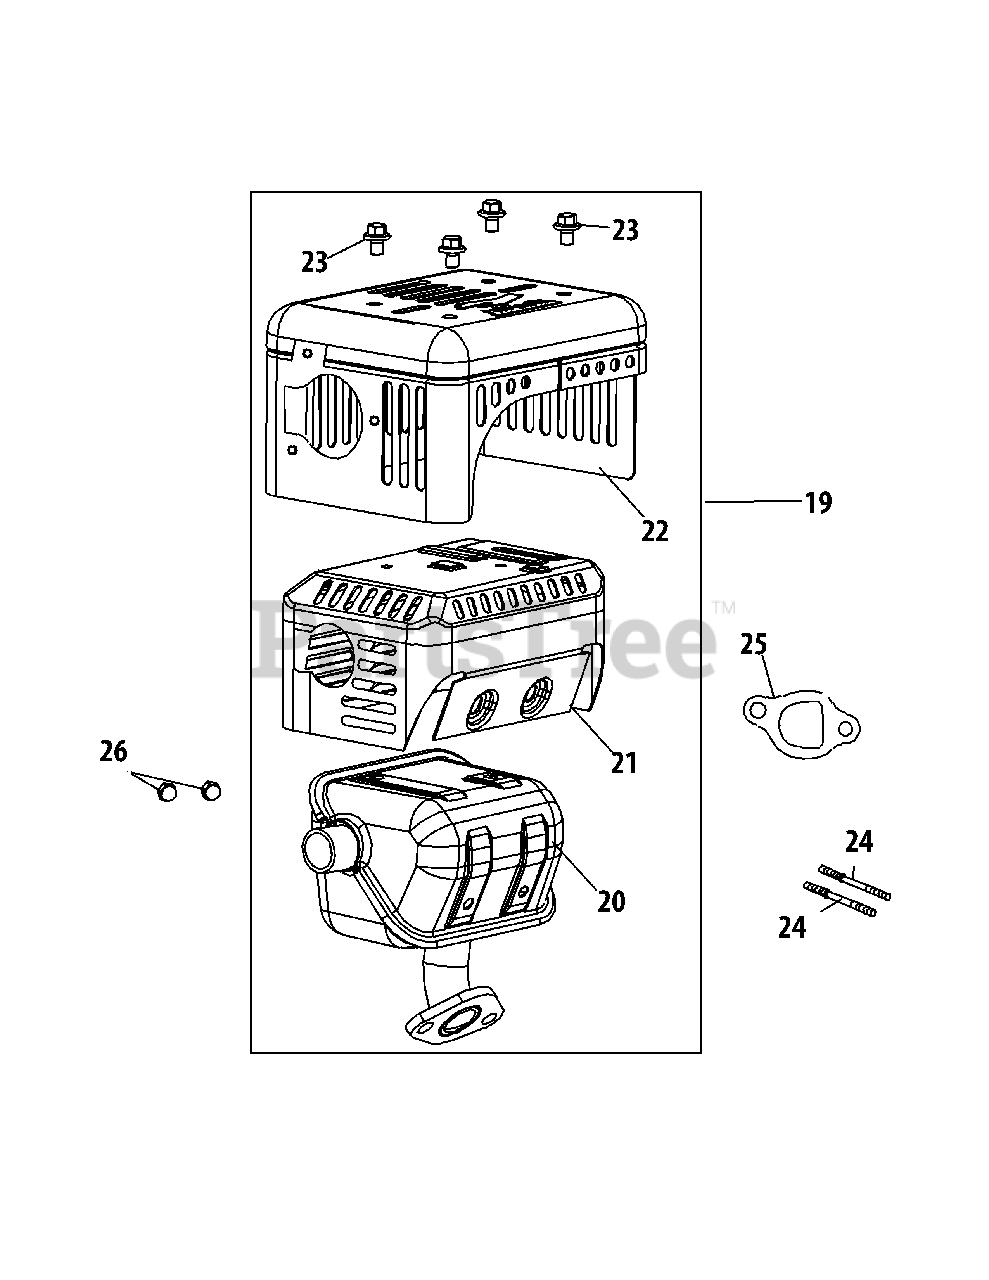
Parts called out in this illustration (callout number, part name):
19	Muffler Assembly
20	Muffler Body
21	Muffler Shield
22	Muffler Guard
23	Bolt M5×8
24	Stud M8×34
24	Muffler Stud Assy
25	Exhaust Pipe Gasket
26	Nut, M8
